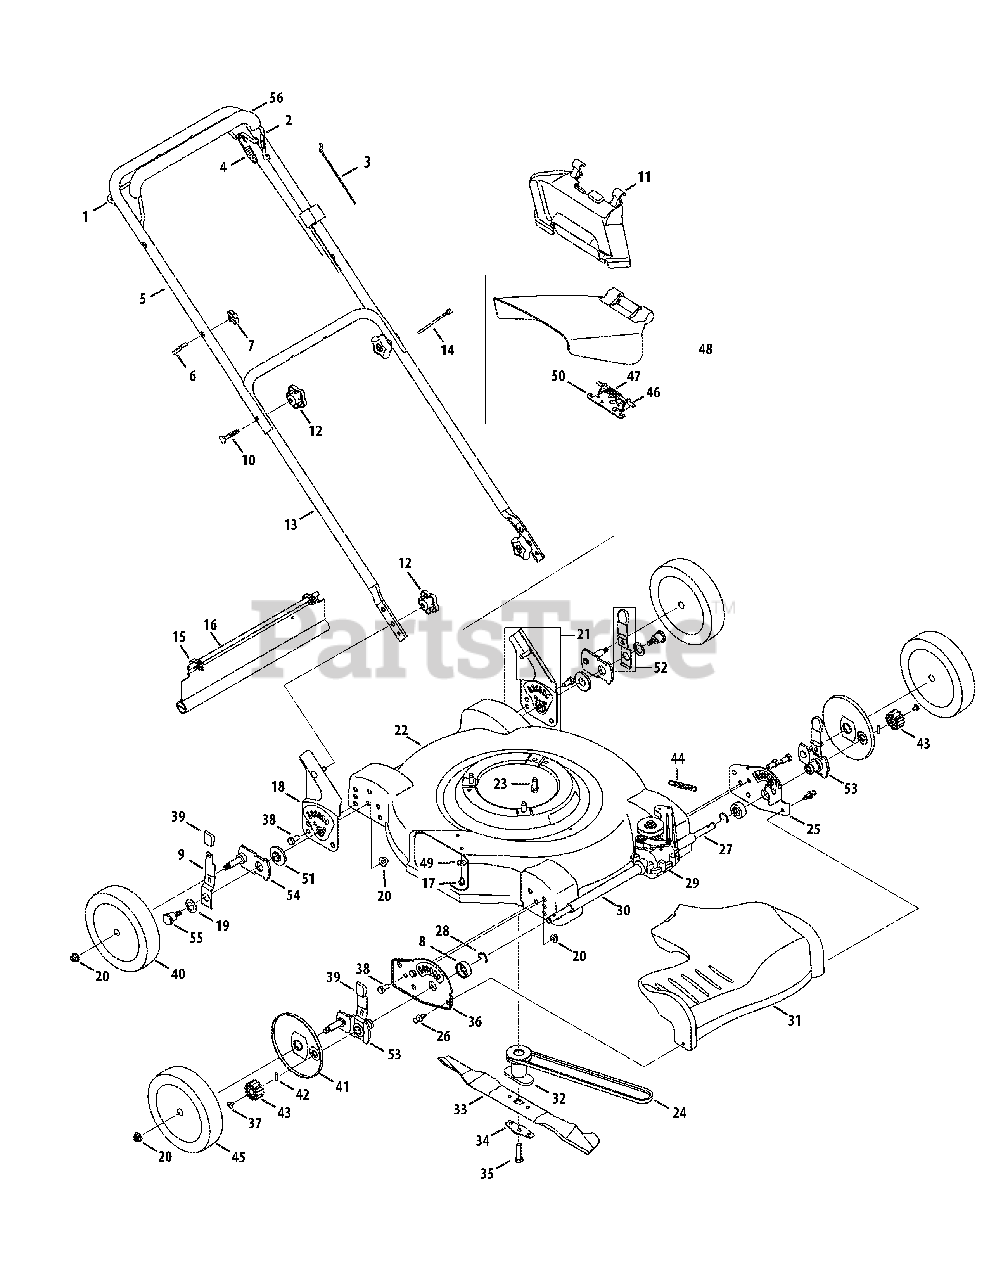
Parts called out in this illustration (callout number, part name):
1	Drive Control
2	Blade Control
3	Control Cable
4	Drive Control Cable
7	Wing Nut, 1/4-20
8	Bearing Support Spacer
9	Spring Lever
10	Carriage Bolt, 5/16-18 x 2.0
11	Mulching Baffle
12	Star Knob
14	Cable Tie
15	Hinge Clip
16	Trail Shield
17	Hex Screw, 1/4-20 x.500
18	Handle Bracket Assy - RH
19	Bell Washer, .760 x 1.25 x.041
20	Lock Nut, 3/8-16
21	Handle Bracket Assembly - LH
22	22" Deck Assembly
23	Hex Washer Scr., 3/8-16 x 1.0
24	V-Belt, 3L x 32.90
25	Forward Height Adj. Plate - LH
27	Sleeve Spacer, .550 ID x 2.22
28	Retainer Ring
29	Transmission Assy. Comp.
30	Sleeve Spacer, .550 ID x 8.51
31	Transmission Cover
32	Blade Adapter
33	22" Mulching Blade
34	Blade Bell Support
35	Hex Cap Screw, 3/8-24 x 1.5
36	Forward Hght. Adj. Plate - RH
37	Screw, 1/4-20 x .390
38	Hex Cap Screw, 3/8-16 x.75
39	Adjustment Knob
40	Rear Wheel
41	Wheel Dust Cover
43	Spur Gear 14T - RH
43	Spur Gear 14T - LH
44	Ext. Spring, .47 OD x 2.50
45	Front Wheel
46	Hinge Pin
47	Torsion Spring
48	Side Discharge Assembly
49	Bell Washer, .265 ID x.75 OD
50	Deflector Chute Adapter
51	Height Adjustment Bearing
52	Rear Hgt. Adj. Lever Assembly
53	Front Lever Assembly
54	Rear Pivot Arm Assembly
55	Shoulder Screw, 3/8-16
56	Deluxe Bail Cover
